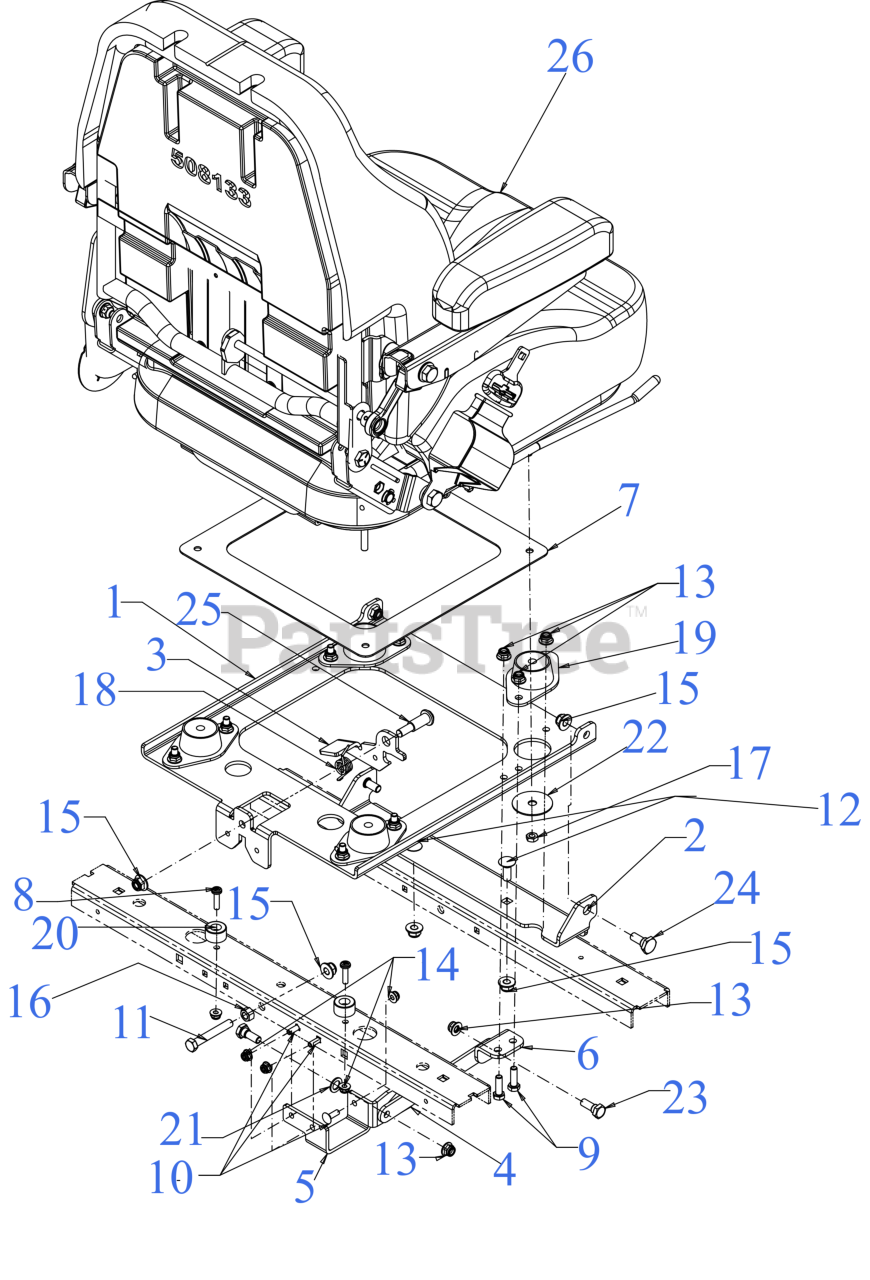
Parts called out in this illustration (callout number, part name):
1	SEAT MOUNTING BRACKET
3	SEAT LATCH LEVER
4	SEAT LOCKOUT BRACKET
5	SEAT LOCKOUT MOUNT
8	MACHINE SCREW 1/4-20:1
9	SCREW 5/16-18 x 1.0 GR5
10	SCREW 1/4-20 x .75 GR5
11	HEX SCREW-3/8-16X2.5 GR5
12	CARRIAGE BOLT 3/8-16 x 1.00 GR5
13	FLANGE LOCK NUT 5/16-18
14	FLANGE LOCK NUT
17	HEX NUT TOP LOCK 5/16-18 GR 8
18	TORSION SPRING
19	SEAT MOUNT
21	FLAT WASHER .469X.750X.054
22	HUB CAP WASHER .406 x 1.92 x .060
23	SHOULDER SCREW .437
24	SHOULDER SCREW
25	SHOULDER SCREW .50X.925
26	SEAT ASSEMBLY (W/ADJUSTABLE LUMBAR)
